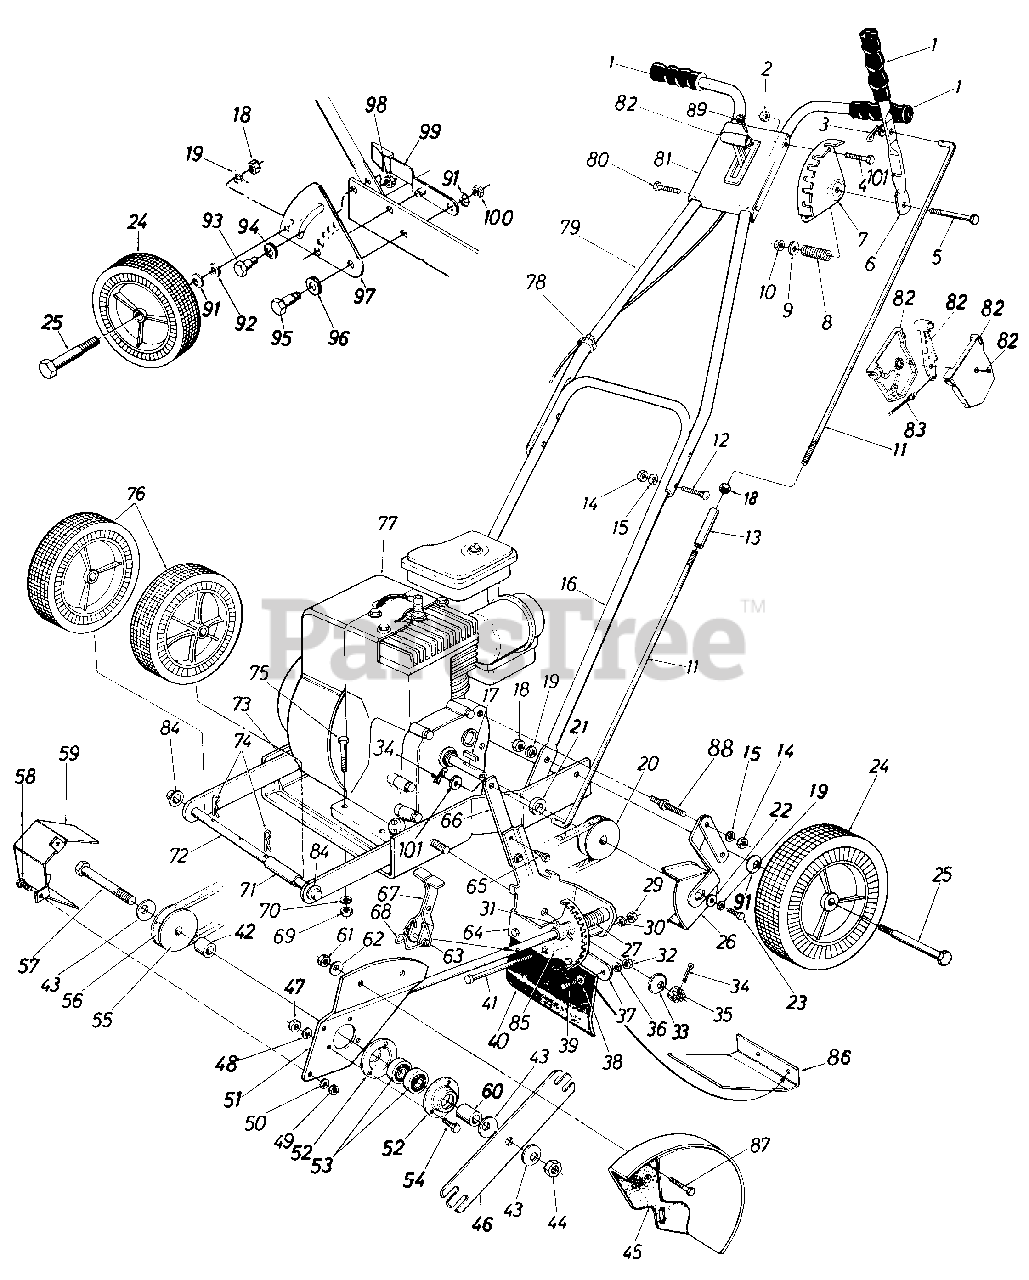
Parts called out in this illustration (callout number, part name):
1	Black Grip
2	Hex L.-Nut 1/4-20 Thd.
3	Cotter Pin 1/8" Dia.
4	Hex Bolt 1/4-20 x 1.25" Lg.
5	Hex Bolt 5/16-18 x 1.75" Lg.
8	Compression Spring 1.38" Lg.
9	Fl.-Wash. .344" I.D.
10	Hex L.-Nut 5/16-18 Thd.
11	Clutch Rod Half 18.25" Lg.
12	Carriage Bolt 1/4 20 x 1.25" Lg.
13	Rod Adjustment Link
14	Hex Nut 1/4-20 Thd.
15	L.-Wash. 1/4" I.D.
16	Lower Handle (Painted)
17	Sq. Key 3/16" x .75" 4.
18	Hex Nut 3/8-16 Thd.
19	L.-Wash. 3/8" I.D.
20	Engine Pulley
21	Spacer .75" I.D.
22	Fl.-Wash. .385" I.D.
23	Hex Bolt 3/8-24 x 1" Lg.
24	Rear Wheel Ass'y. 8" x 1.75"
25	Shoulder Bolt .498" Dia.
26	Belt Guard Ass'y.
27	Compression Spring
29	Hex Nut 5/16-18 Thd.
30	L.-Wash. 5/16" I.D.
31	Spring Pin Spir. 3/16" Dia.
32	Hex Nut 1/4-20 Thd.
33	Bell.-Wash. .535" I.D.
34	Cotter Pin 1/8" Dia.
35	Hex Slotted Nut 1/2-20 Thd.
36	L.-Wash. 1/4" I.D.
39	Hex Bolt 1/4-20 x .50" 4.
41	Hex Bolt 5/16-18 x 4.5" 4.
42	Spacer 1.030" 4.
43	Bell.-Wash. .63" I.D.
44	Hex Ins. L.-Nut 5/8-18 Thd.
47	Hex Nut 1/4-20 Thd.
48	L.-Wash. 1/4" I.D.
49	Hex Nut 1/4-20 Thd.
50	L.-Wash. 1/4" I.D.
53	Ball Bearing .62" I.D.
54	Hex Bolt 1/4-20 x .62" Lg.i'
55	3/8""V"Pulley
56	"V"Belt
57	Hex Bolt 5/8-18 x 4.5" Lg.
58	Hex Bolt 1/4-20 x .625" Lg.
60	Sleeve.90" Lg.
61	Hex Nut 5/16-18 Thd.
62	Bell.-Wash. .345" I.D.
63	Spring Pin Spir. 1/4" Dia.
68	Torsion Spring
69	Hex Nut 5/16-18 Thd.
70	L.-Wash. 5/16" I.D.
71	Spacer 1.62" Lg.
72	Axle 8.75" Lg.
73	Base Ass'y.
74	Hair Pin Cotter 1/2" Dia.
75	Hex Bolt 5/16-18 x 1.5" Lg.
76	Front Wheel Ass'y. 7" x 1.50"
77	Engine
78	Cable Tie
79	Upper Handle (Painted)
80	Hex Bolt 1/4-20 x 1" Lg.
83	Throttle Control Wire 30" Lg.
84	Push Cap 1/2"Dia.
85	Spacer 3.765" Lg.
88	Stud 1/4-20 x 2.12" Lg.
89	Self-Tap Scr. #10 x .50" Lg.
91	Bell.-Wash. .40" I.D.
92	Fl.-Wash. .39" I.D.
93	Shld. Bolt.5" Dia.
94	Bell-Wash. .515" I.D.
95	Shld. Bolt .50" Dia.
96	Fl.-Wash. 51" I.D. x l"
99	Spring Adj. Lever
100	Hex Jam Nut 3/8-16 Thd.
101	Fl-Wash. 3/8" I.D.
